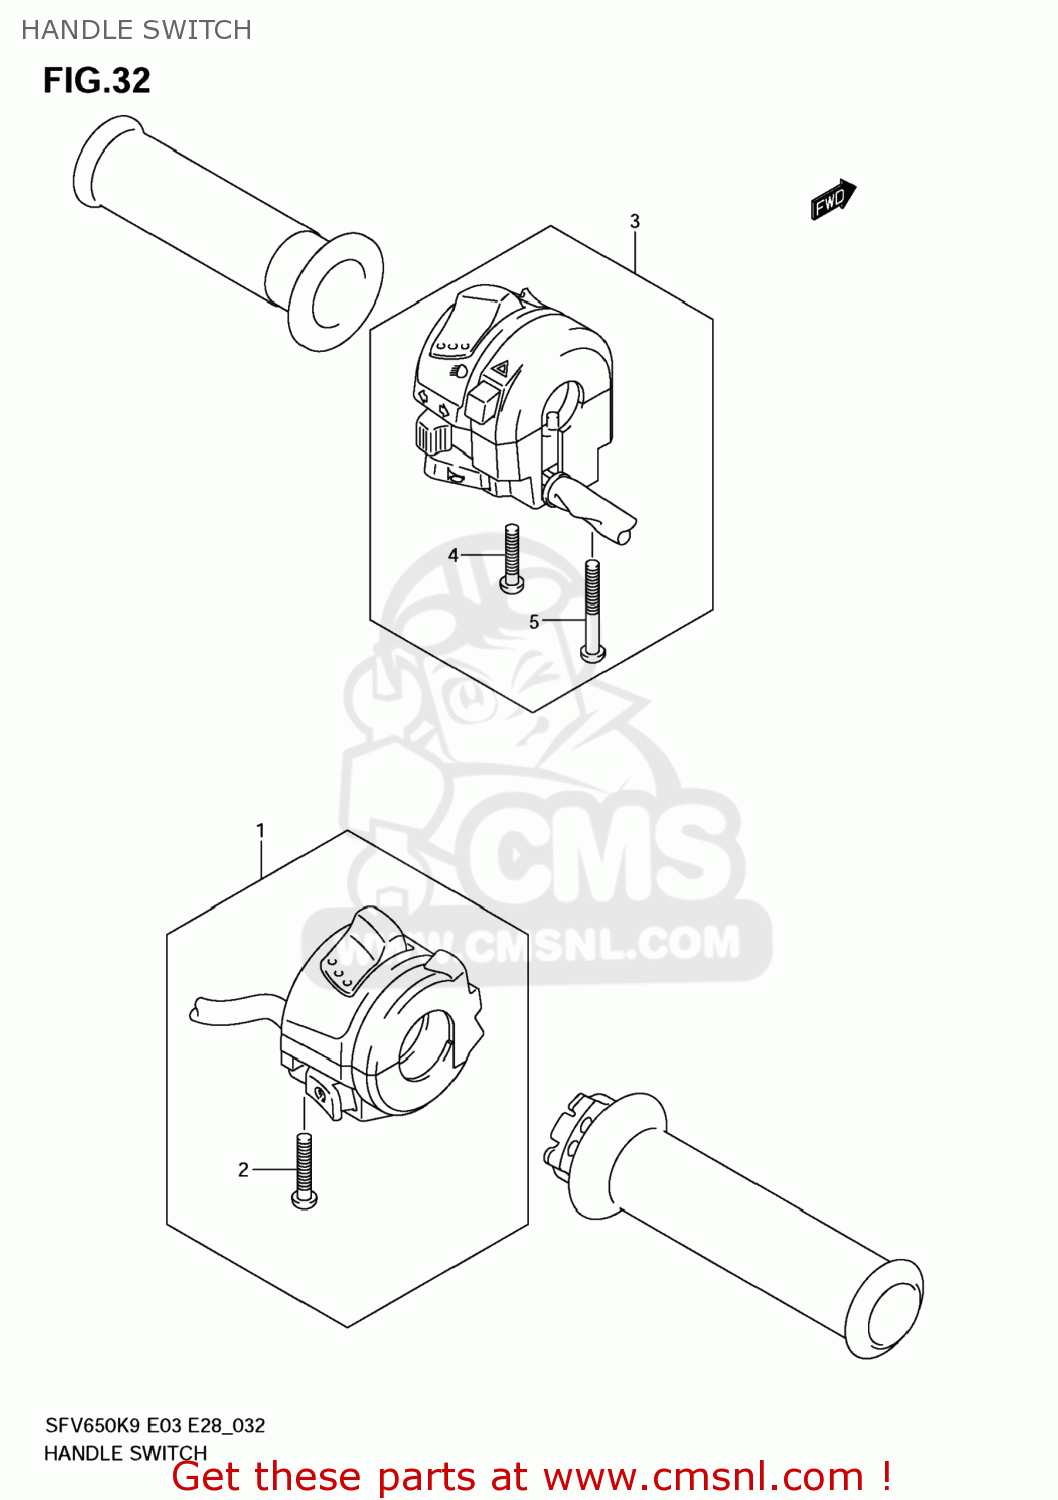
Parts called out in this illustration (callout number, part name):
1	SWITCH ASSY,HANDLE,R
2	SCREW
3	SWITCH ASSY,HANDLE,L
4	SCREW
5	SCREW
